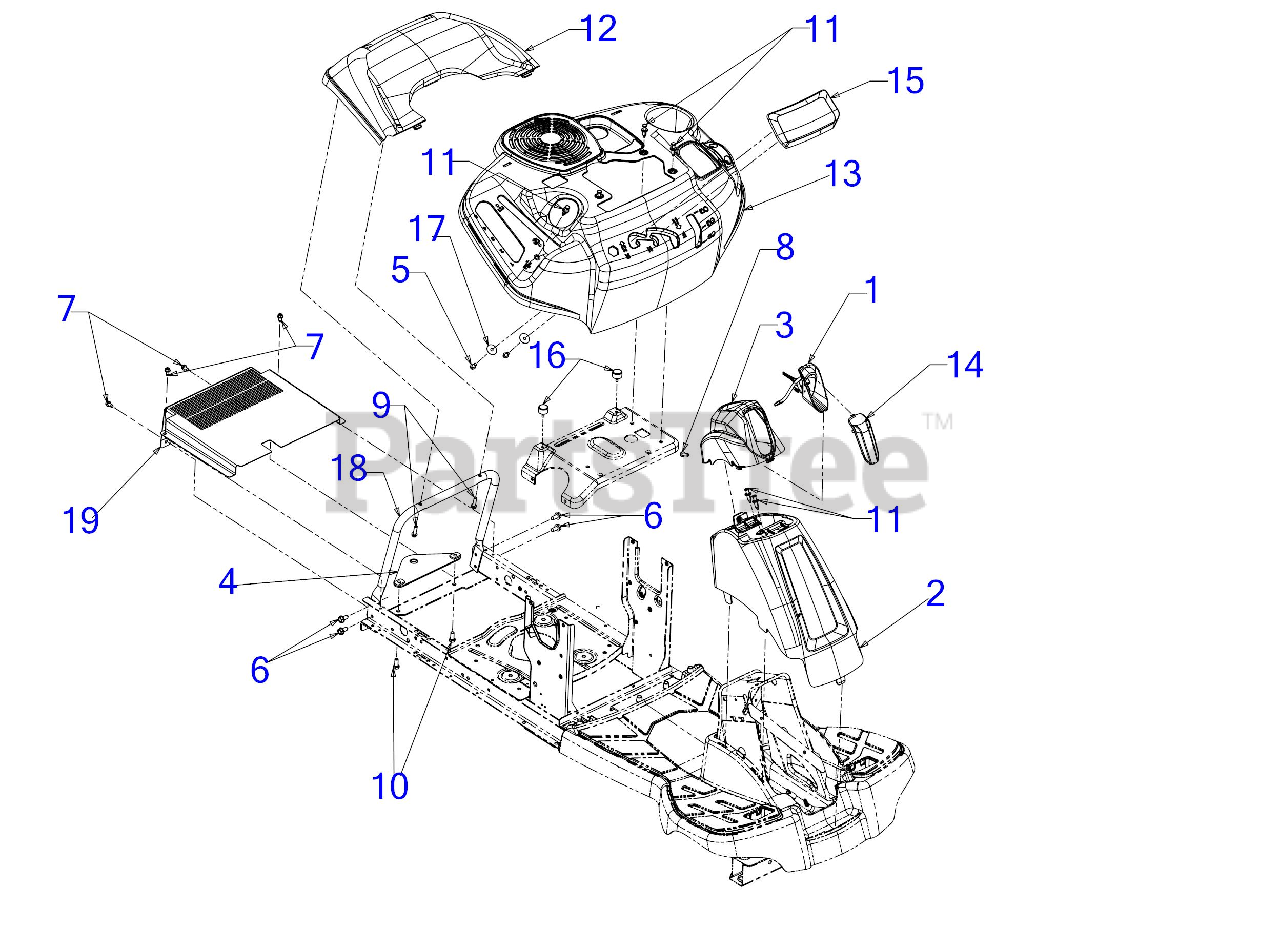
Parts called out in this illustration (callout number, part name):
1	HEADLIGHT HARNESS ASSEMBLY
2	COLUMN COVER ASSEMBLY (ORANGE)
3	COLUMN CAP
5	HEX SCREW 1/4-15 x .50
6	SCREW 5/16-18 x .750
7	SCREW 1/4-20 X.500
8	SCREW 1/4-20X.75
9	SCREW 1/4-15 x 1.00
10	SCREW 5/16-18 x .75 GR5
11	PLASTIC RIVET
12	REAR COVER
13	FENDER
14	LED HEADLIGHT LENS
15	FENDER COVER
16	BUMPER .62 DIA x .50
17	FLAT WASHER
19	HYDRO COVER HEAT SHIELD (B&S)
